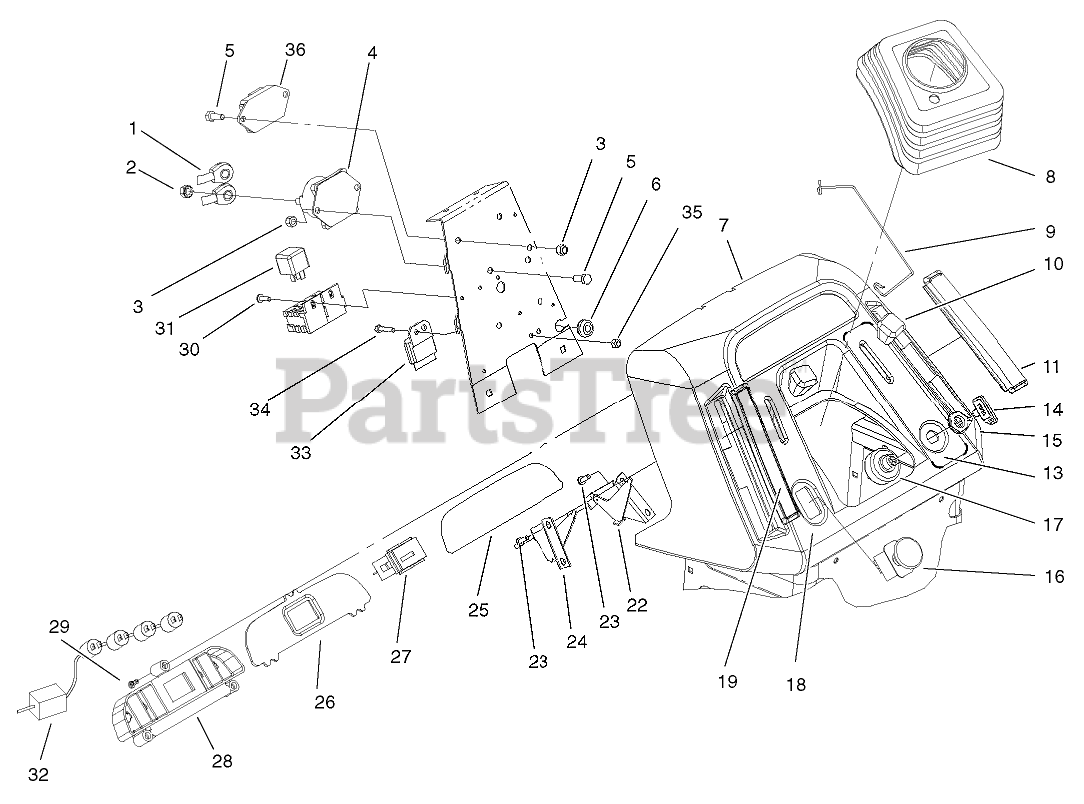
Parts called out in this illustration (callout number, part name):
1	CABLE-BATTERY, RED
2	NUT-KEPS
3	NUT-LOCK, NI
4	SOLENOID
5	SCREW-HH
6	GROMMET-RUBBER
8	BOOT-STEERING
9	CLIP-BOOT
11	COVER-SLOT, RH
13	Decal-Dash (only on: 72072)
13	Decal-Throttle, Ignition (only on: 72052)
14	KEY-IGNITION
16	SWITCH-PTO
17	SWITCH-IGNITION
18	Decal-Dash PTO/Choke (only on: 72072)
18	Decal-PTO/Choke (only on: 72052)
19	COVER-SLOT, LH
22	CONTROL-THROTTLE
24	CONTROL-CHOKE
25	DECAL-LENS, DASH
26	LENS-DASH
27	HOURMETER
28	HOUSING-LIGHT, INDICATOR
29	SCREW
30	SCREW-PPHTF
31	RELAY
32	HARNESS-4 LAMP
33	MODULE-LOW VOLTAGE
35	NUT-LOCK, NI
36	MODULE-CLUTCH
